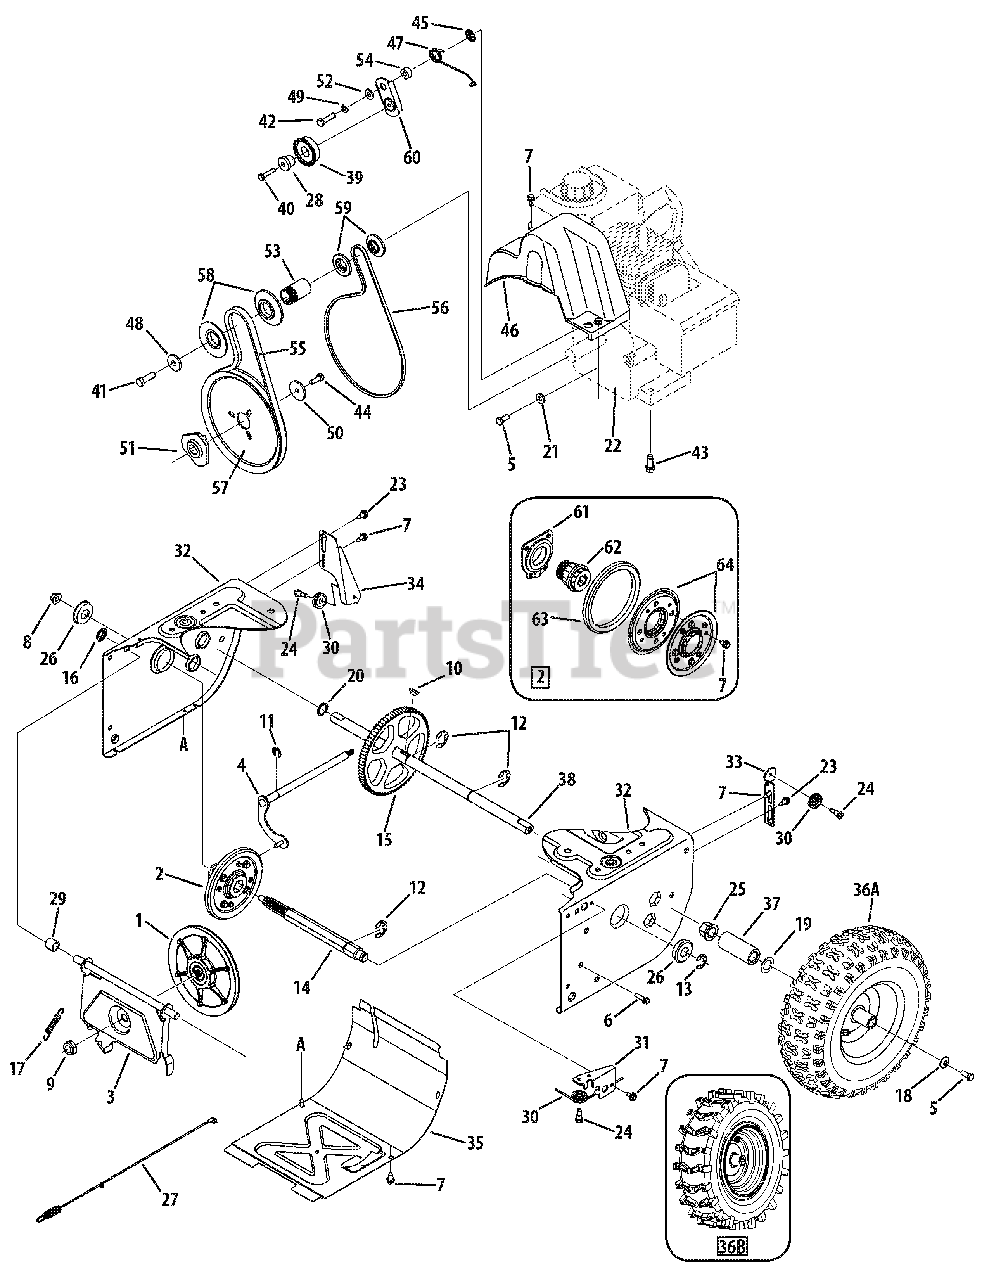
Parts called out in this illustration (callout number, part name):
1	Disc Assmbly, Friction Wheel
2	Friction Wheel Assembly, 5.5 OD
4	Rod Shift Assembly
5	Hex Screw, 5/16-24 x .750
6	Screw, 1/4-20 x 1.000
7	Screw, 1/4-20 x .625
8	Flange Lock Nut, 3/8-16, Nylon
9	Jam Lock Nut, 5/8-18, Nylon
10	Hi-pro Key, 6/16 x 3/4 Dia
11	E-Ring, .500 Dia
12	Retaining E-Ring, .875 Dia
13	E-Ring, .750 Dia
14	Hex Shaft, .8125, 7-Tooth
15	Gear, 80-Tooth
16	Speed Nut, .500
17	Extension Spring
18	Bell Washer, .340 x .872 x .060
19	Flat Washer, .793 x 1.24 x .060
20	Flat Washer, .75 x 1.00 x .060
21	Shoulder Spacer
23	Shoulder Screw, .37 x .105, 1/4-20
24	Screw, 1/4-28, .375
25	Hex Flange Bearing
26	Ball Bearing, 17 x 40 x12
27	Wheel Clutch Cable, 44.95''
28	Shoulder Spacer, .26 x .79 x .538
29	Spacer, .508 iD x .75 OD x .68
30	Cable Roller
36A	Wheel Assy
37	Spacer, 1.25 x .75 x 3.0
38	Axle, .75 x 22''
39	Idler Pulley Assembly
40	Hex Screw, 1/4-20 x 1.25
41	Hex Screw, 3/8-24, 1.25
42	Hex Screw, 5/16-24, 1.25
43	Sems Screw, 3/8-16 x 1.00
44	Hex Screw, 5/16-24 , .875
45	Push-On Nut, .25 Dia
46	Belt Cover
47	Torsion Soring, .850 ID x .354
48	Flat Washer, .34 x 1.50 x .150
49	Lock Washer, .3125
50	Flat Washer, .406 x 1.25 x .157
51	Adapter Pulley, .75 Dia
52	Shoulder Spacer, .317 x .50 x .102
53	Spacer, .875 ID x 1.185 OD
54	Spacer, .340 x .750 x .360
55	Auger Drive Belt
56	Wheel Dribe Belt
57	Auger Drive Pulley, 8.1 x .5
58	Pulley Half, V x 2.600 OD
59	Pulley Half, 1/4-V x 1.5 OD
60	Wheel Drive Idler Bracket
61	Bearing Assembly
62	Friction Wheel Hub
63	Friction Wheel Rubber
64	Friction Wheel Plate
